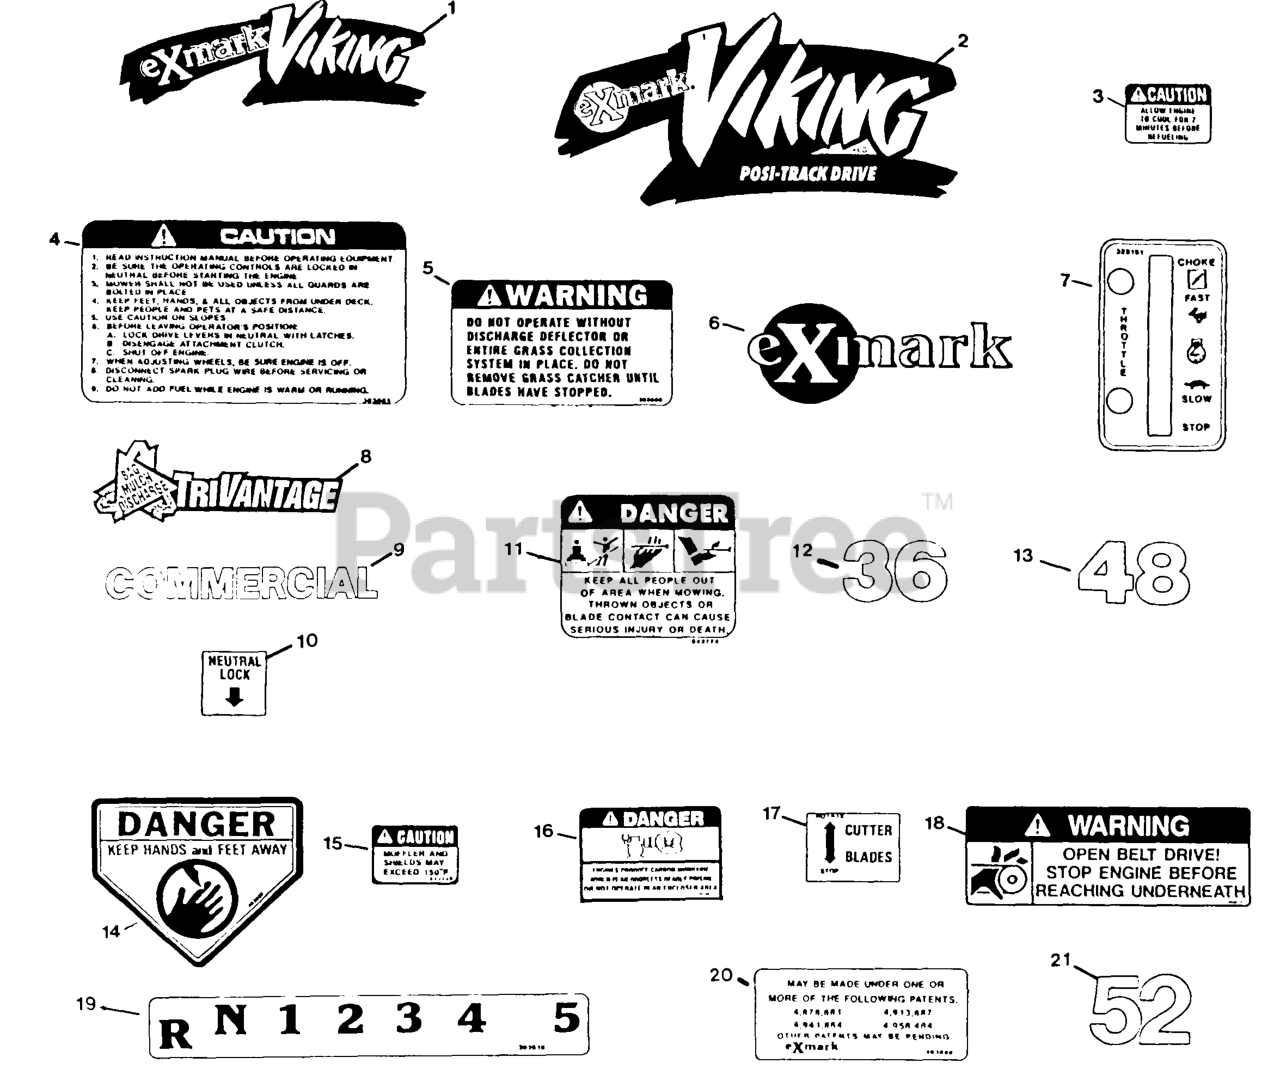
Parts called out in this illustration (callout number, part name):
4	LABEL,INSTRUCTION
5	DECAL-WARNING, DISCHARGE
10	DECAL,NEUTRAL LOCK
11	DECAL-DANGER
14	DECAL-DANGER
17	DECAL,CUTTER BLADE
18	DECAL,BELT DRIVE
19	DECAL,SHIFTER
